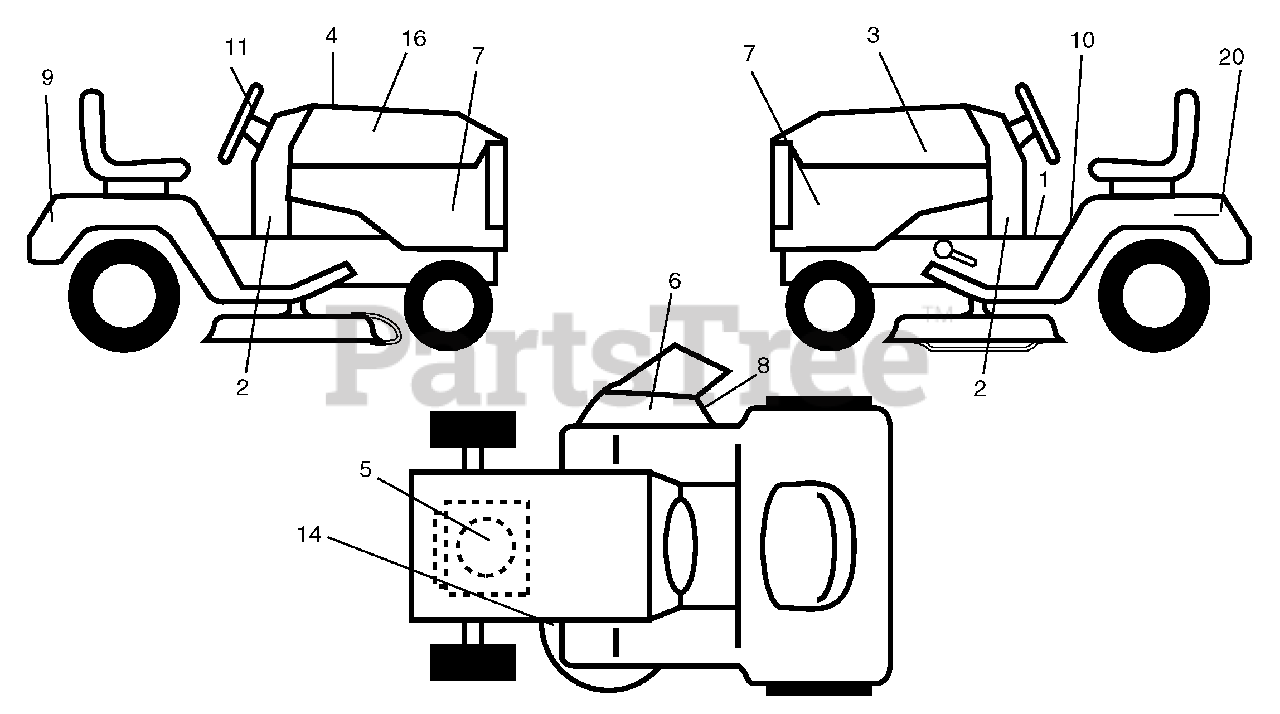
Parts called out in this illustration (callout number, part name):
1	Decal, Oper
2	Decal, Lower Dash
3	Decal, Hood LH
4	Decal, Replace
5	Decal, HP Engine
6	Decal, Deck "B" 42"
7	Decal, Side Panel
8	Decal, Warning Mult-Language
9	Decal, Fender Logo
10	Decal, Fender Danger E/F
11	Decal, Ins Strg Whl
14	Decal, V-Belt Schematic
16	Decal, Hood Rh
20	Decal, Bat Dan/Psn
20	Decal, Handle Lft Height Adjust
